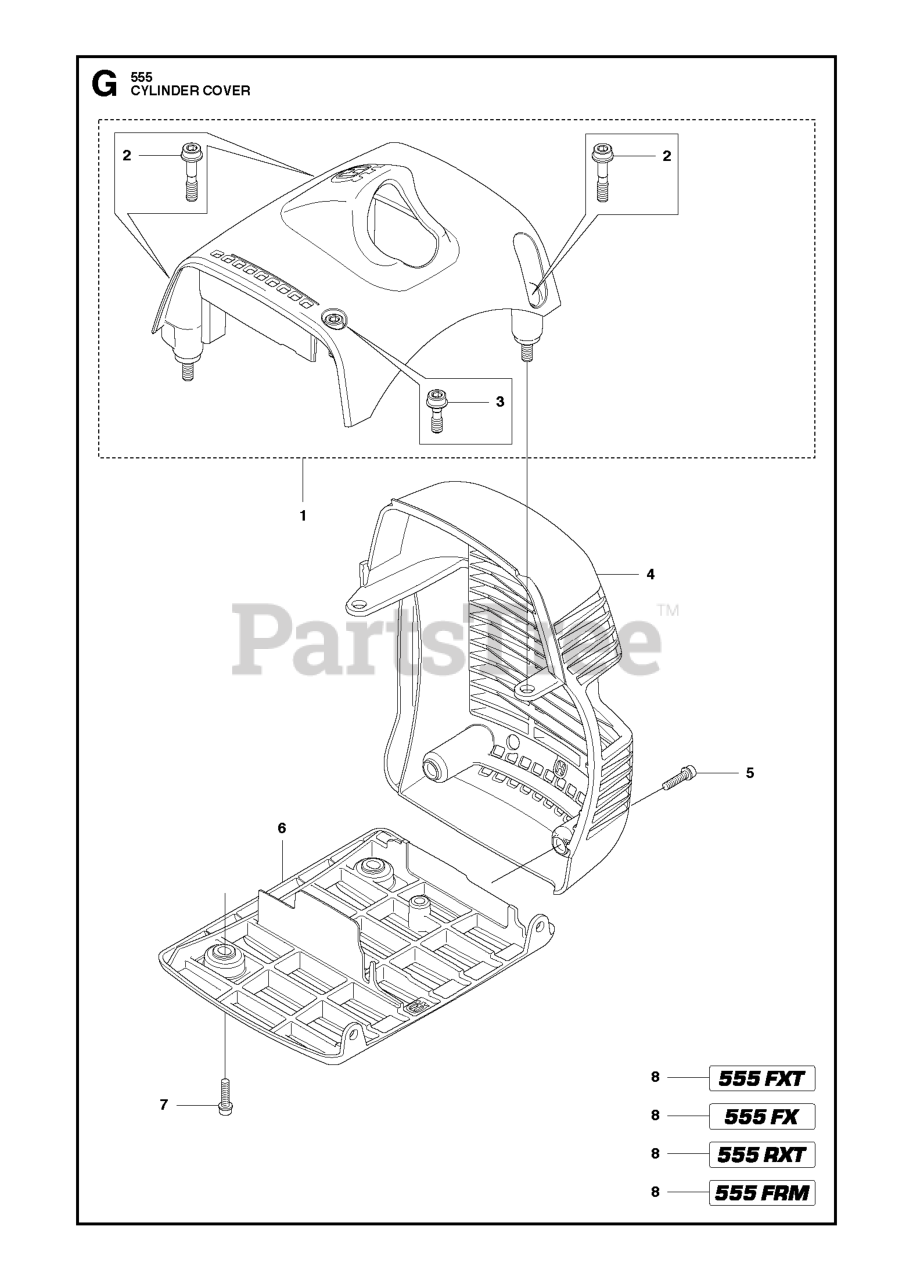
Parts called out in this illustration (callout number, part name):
1	CYLINDER COVER ASSY SPARE PAR
2	SCREW IHSCFMO
3	SCREW IHSCFMO
4	HEAT PROTECTOR
6	PROTECTIVE COVER ASSY HUSQ
8	LABEL CYLINDER COVER 555 FX
8	LABEL CYLINDER COVER 555 FRM
8	LABEL CYLINDER COVER 555 FXT
8	LABEL CYLINDER COVER 555 RXT
